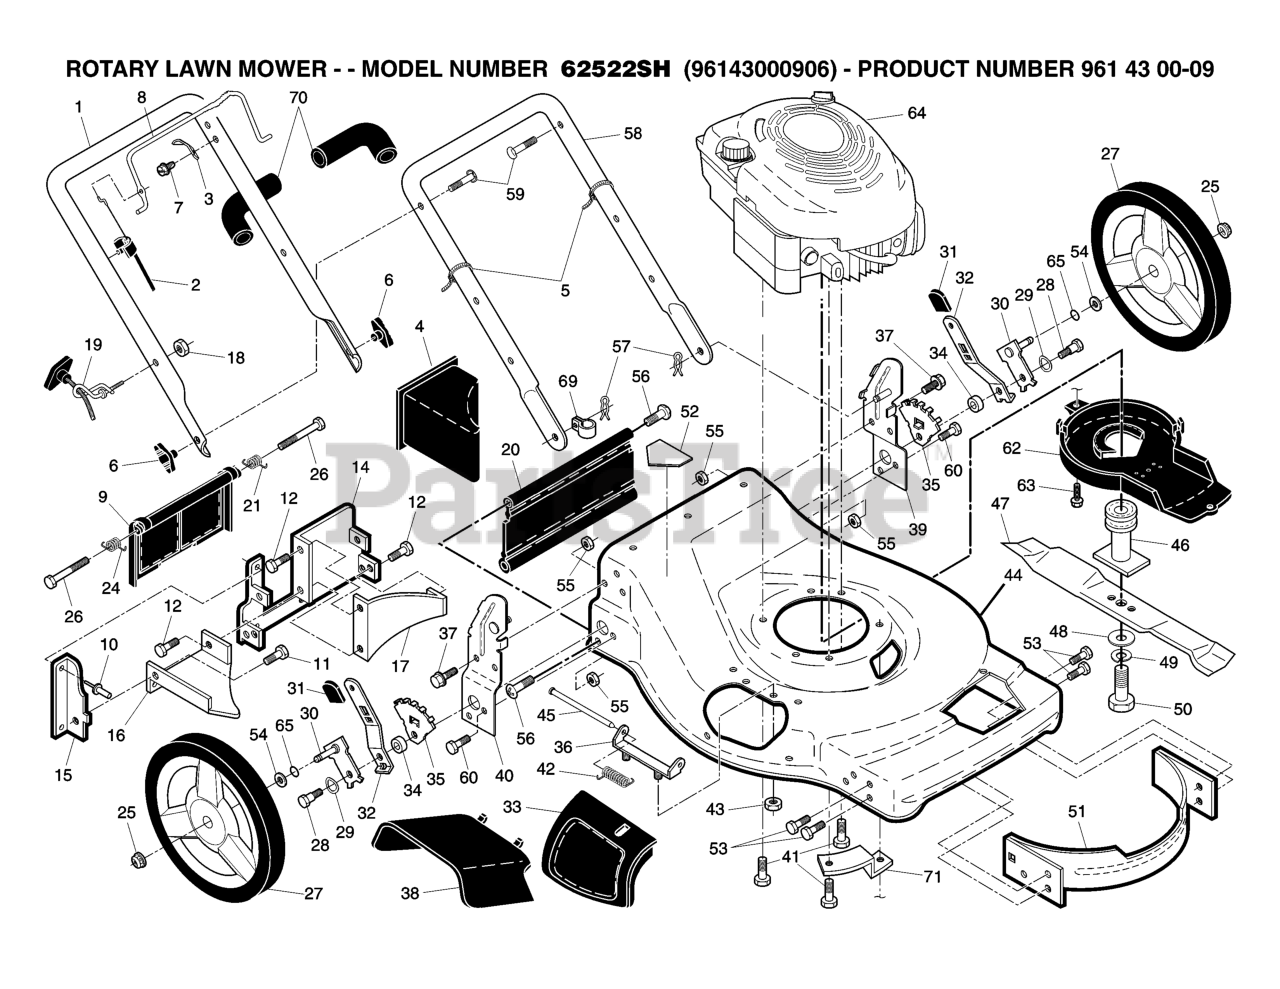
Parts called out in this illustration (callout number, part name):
1	HANDLE.ASM.UP.OFF/EZ.CR.W/GRIP
2	CABLE.ENGINE BRAKE.MZR
3	BRACKET UPSTOP
4	PLUG.MULCH.22RD
5	TIE GUIDE
6	HNDL.KNOB.GRAY
8	BAIL.DSTRT.FL.AW.CREAS.ORANGE
9	REAR DOOR ASSY
10	RIVET BLIND
11	SCREW.HXTAP.10-24
14	PLATE.BACK
15	SIDE BAFFLE
16	DISCHARGE BAFFLE
17	REAR BAFFLE
18	NUT
19	RB GUIDE.ROPE.STD.BLK.ZIN WSL
20	SKIRT
21	SPRING.LH.22.REAR.DOOR.EZ.EMPT
24	SPRING.RH.22.REAR.DOOR.EZ.
25	NUT
27	RP.WHEEL.12X1.75H 3 SPOKE.RAD
28	BOLT
29	WASHER.CURVED.CYLINDRICAL
30	ARM.ASM.AXLE.5/9.POS.BZP
31	KNOB.DELUXE.GRAY
32	SELECTOR SPRING
33	DOOR.MULCH.22.REAR.FWGD.GREY
34	SPACER.HEIGHT.ADJUSTER
35	WHEEL ADJ BRACKET
36	BRACKET.ASM.HINGE.21.FWGD.
37	SELF-TAPPING SCREW 5/16-18X3/4
38	DEFLECTOR.CLIPPING.22.FGD
39	BRKT.ASM.HND
40	BRKT.ASM.HND
41	BOLT 3/8-16X1-1/8
42	SPRING.TORSION
43	LOCKNUT.NYLOC.1/4-20
44	KIT, MOWER HOUSING
45	ROD.HINGE.21
46	RP ADAP.BLDE/PULL
47	BLADE.22.MULCH.STANDARD
48	WASHER,HARDEN
49	LOCKWASHER
50	SCREW, HEX HD 3/8-24 X 1-3/8
51	FRONT BAFFLE KIT
52	DANGER DECAL
53	SCREW 1/4X20
54	WASHER.FLAT.1/2
55	LOCKNUT PM
56	HINGE SCREW
57	HAIRPIN COTTER
58	HANDLE
59	BOLT, HANDLE 5/16-18X1.75
62	DEBRIS SHIELD
63	SCREW.HEX.WSH
65	O-RING..070X.487.NEOPRENE
69	CLIP.CABLE.BLK
70	GRIP.HANDLE.FOAM.WIDE.(1 SIDE)
71	BRACKET
